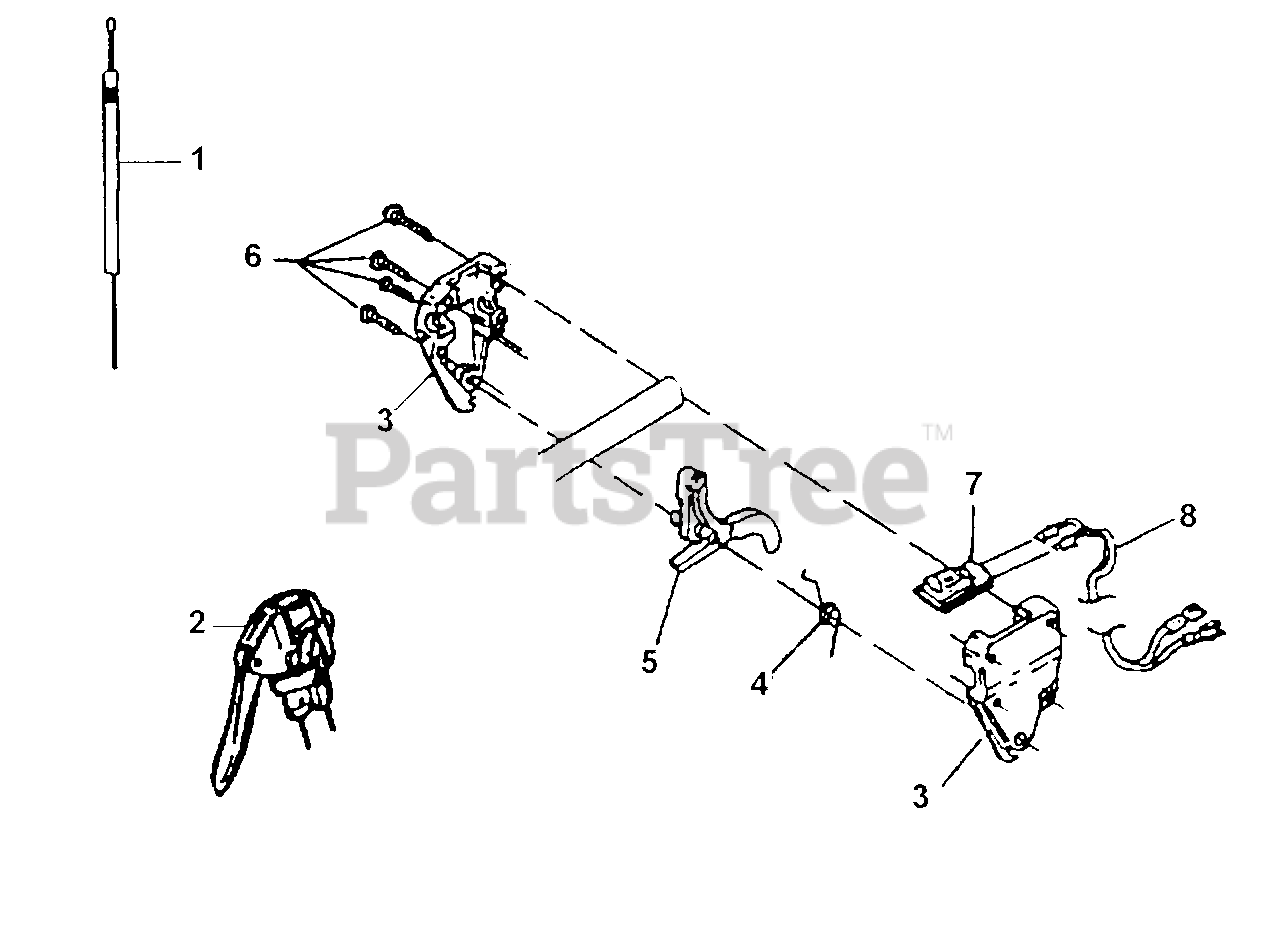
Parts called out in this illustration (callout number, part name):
1	THROTTLE CABLE (4000j)
1	THROTTLE CABLE (4000b)
2	THROTTLE SWITCH ASSY (4000b)
3	THROTTLE HOUSING KIT (4000j)
4	SPRING, THROTTLETRIGGER
5	THROTTLE LEVER
6	SCREW
7	STOP SWITCH (4000j)
8	WIRE HARNESS (4000j)
